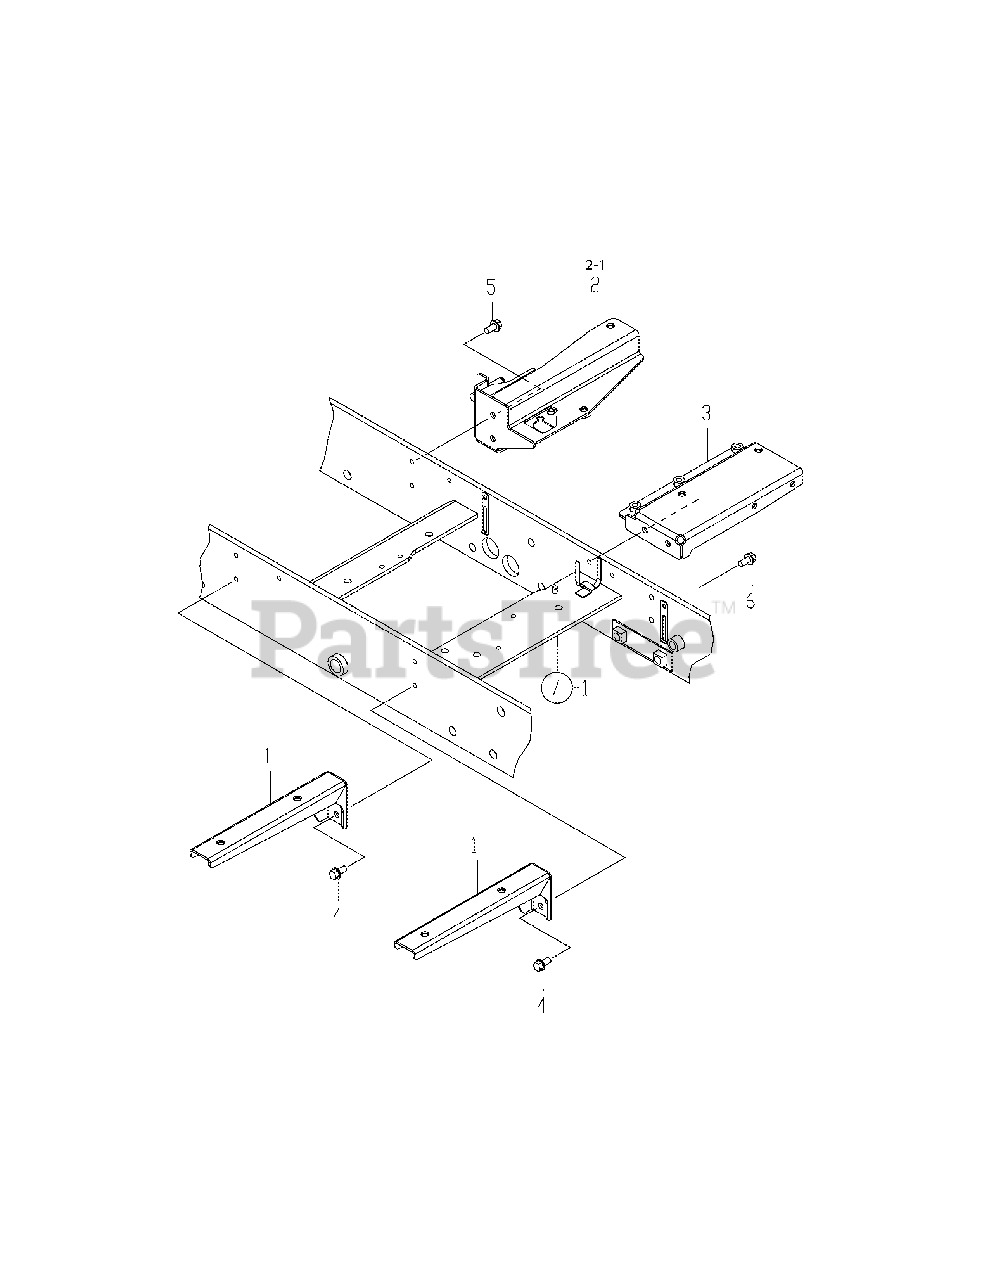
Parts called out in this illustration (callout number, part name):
1	Stay L, Step Cmp
2	Stay Rf, Step Cmp
2-1	Stay Rf, Step Cmp
3	Stay Rr, Step Cmp
